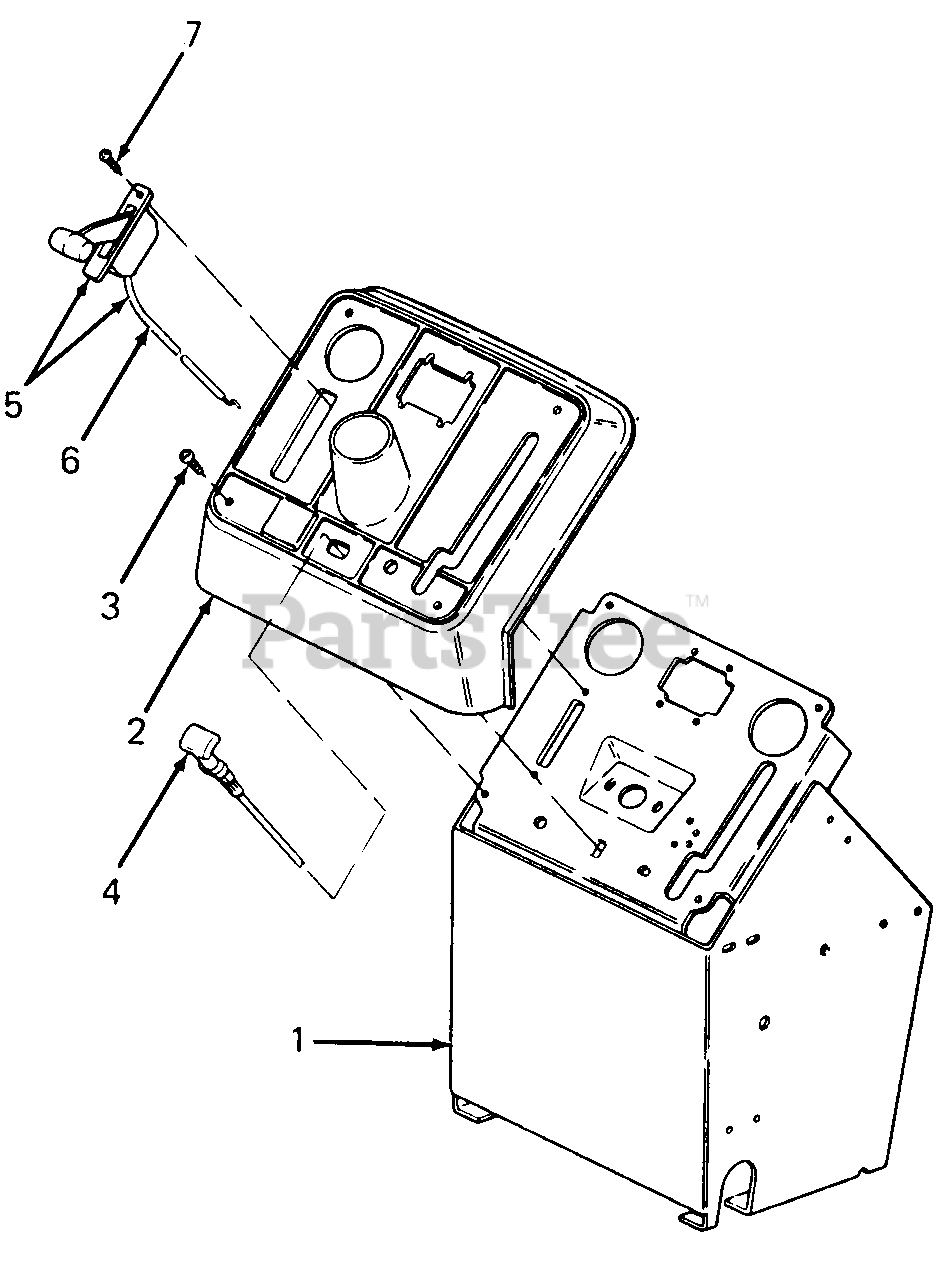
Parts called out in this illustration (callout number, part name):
2	Panel, Dash
3	Screw, Pan Hd Cutting, #10-24 X .75 Lg
4	Control, Choke
5	Control Assy, Throttle - Complete
6	Wire, Throttle Control
7	Screw, Truss Mach AB Tapp, #10 X .50 Lg
